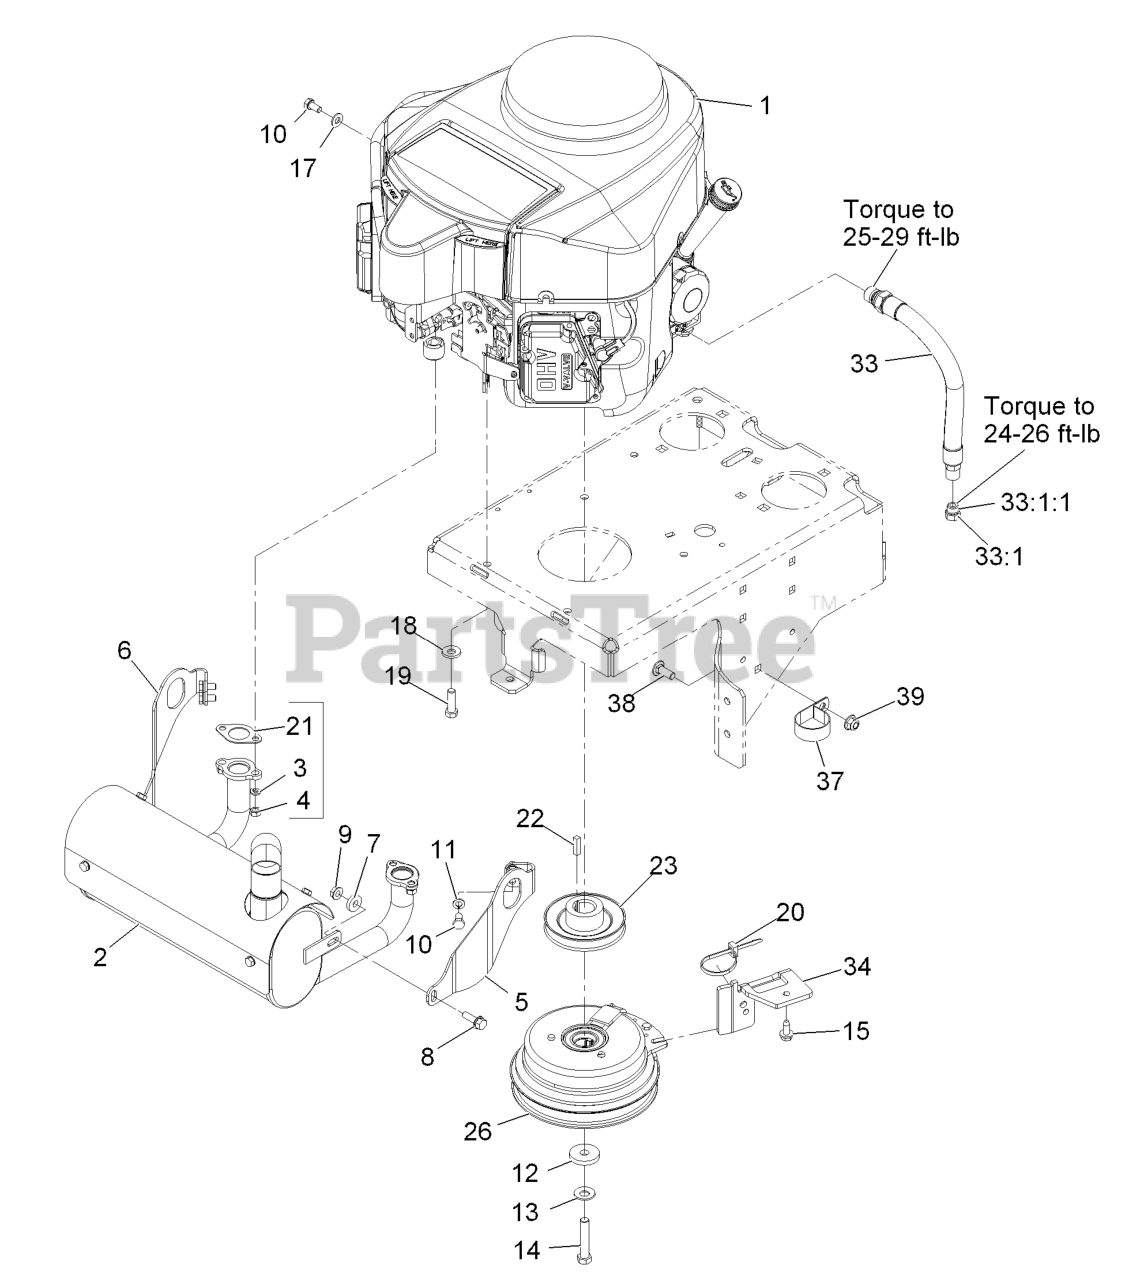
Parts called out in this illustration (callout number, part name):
1	Engine-Kawasaki, Fs691v-As12 (24 Hp)
3	WASHER-LOCK
5	BRACKET-MUFFLER MOUNT, LH
6	BRACKET-MUFFLER MOUNT, RH
8	SCREW-HHF
10	SCREW-HH
11	WASHER-LOCK
12	WASHER
13	WASHER-SPRING
14	SCREW-HH
15	Screw-HWH 5/16-18 X 3/4 Tf
17	WASHER-PLAIN
18	WASHER-BELLEVILLE
19	SCREW-HH
20	TIE-CABLE
21	GASKET-EXHAUST
26	CLUTCH-WARNER
33	ENGINE OIL DRAIN HOSE ASM
33:1	PLUG-HH
33:1:1	O-RING
34	BRACKET-ANCHOR, CLUTCH
37	CLAMP-R
38	SCREW-CARR
39	NUT-HF, NI
